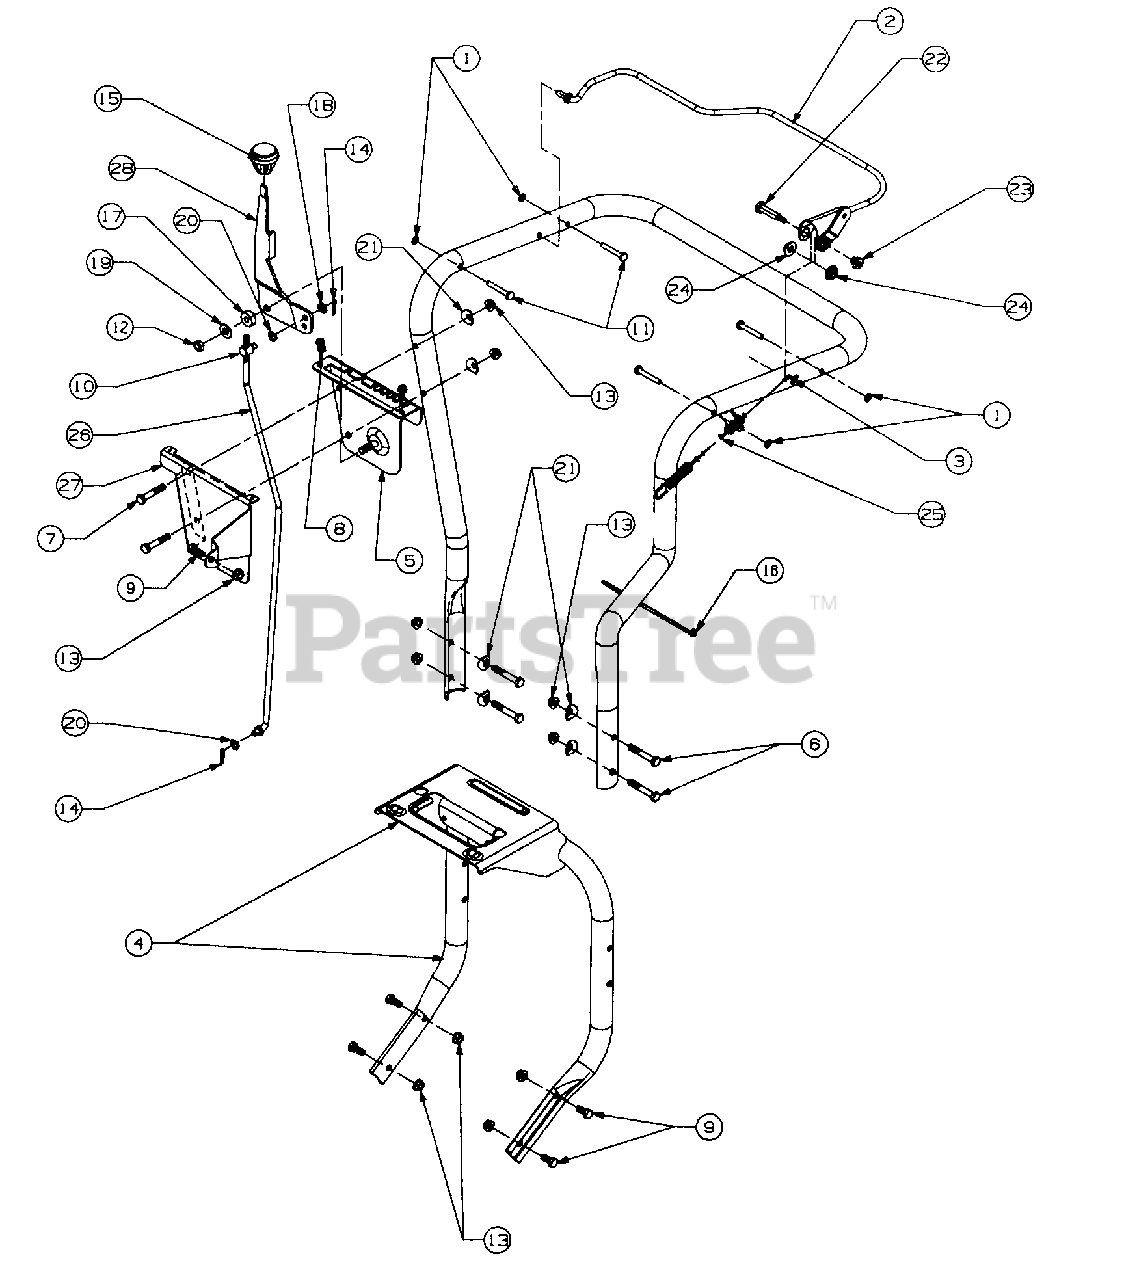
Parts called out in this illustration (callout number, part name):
7	SCREW-HEX
8	SCREW-HEX
9	SCREW-HEX
10	FERRULE
11	PIN-STUD
12	NUT-HEX LOCK
13	NUT-HEX LOCK
14	PIN-COTTER
15	KNOB-SHIFT
16	CABLE TIE
17	WASHER-RUBBER
18	WASHER-FLAT
19	WASHER-FLAT
20	WASHER-SPRING
21	WASHER-SADDLE
22	SCREW-SHOULDER
23	NUT-SHOULDER
24	BEARING-FLANGE PLASTIC
25	CABLE-CLUTCH
26	ROD-SHIFT
